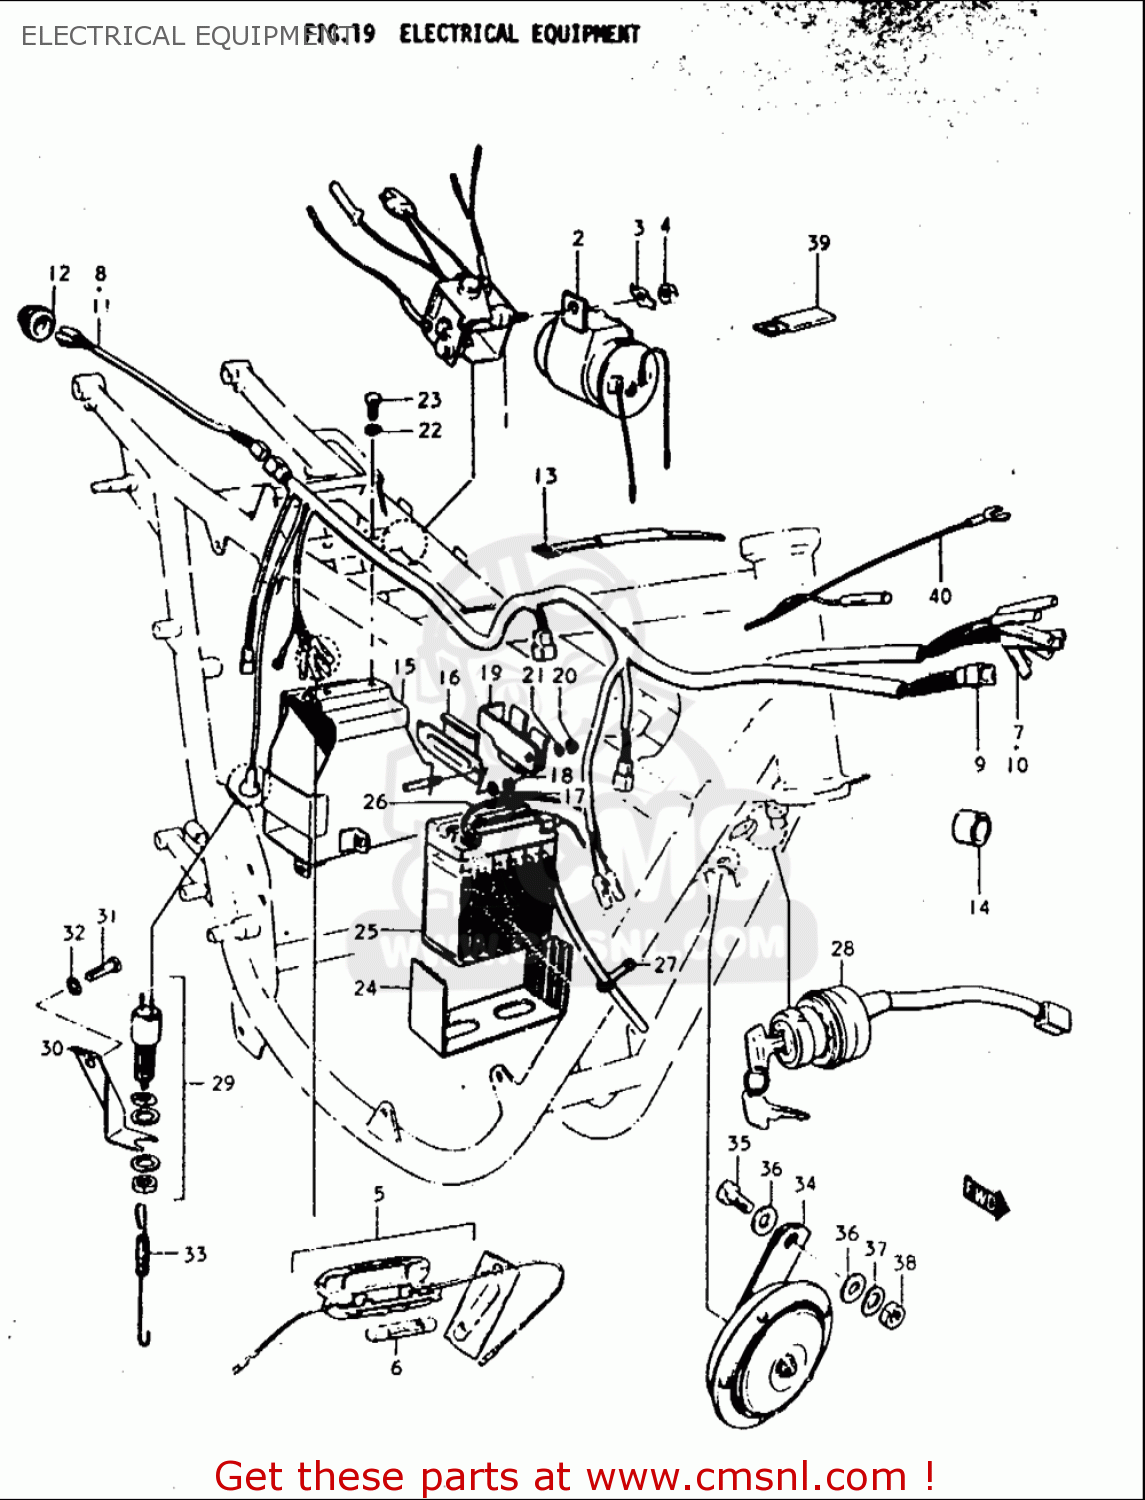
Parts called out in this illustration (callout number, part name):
1	RECTIFIER ASSY
2	RELAY,TURN SIGNAL
4	NUT
5	CASE ASSY,FUSE
6	FUSE(15A)
13	CLAMP
17	WASHER,LOCK
18	NUT
20	NUT
21	WASHER,LOCK
22	WASHER,LOCK
23	BOLT
25	BATTERY ASSY(YB5L-B,12V5.3AH)
28	SWITCH ASSY,IGNITION
29	SWITCH ASSY,BRAKE LAMP
32	WASHER,LOCK
33	SPRING
35	BOLT
36	WASHER
37	WASHER,LOCK
38	NUT
39	CLAMP(L:120 T:1.0)
40	CORD, HANDLEBAR EARTH
